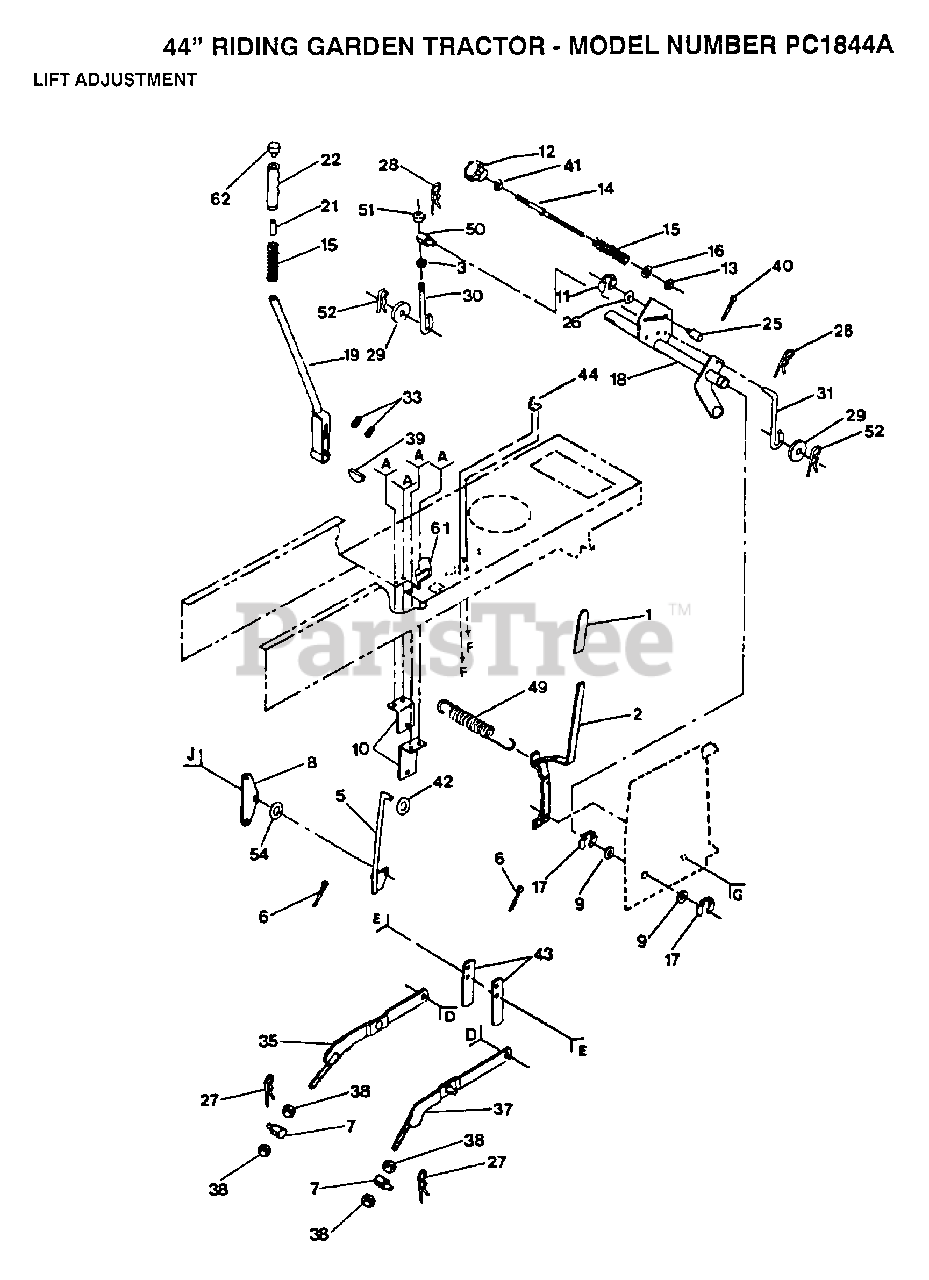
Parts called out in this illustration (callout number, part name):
5	ROD ASSEM YT
6	COTTER PIN
8	"T, BELLCRANK"
9	WASHER
10	"BRKT,BELLCRAN T"
11	KLIP RING
13	NUT T
14	ROD LIFT LT
15	SPRING T
16	WASHER
17	E-RING
22	GRIP
23	BOLT LT
25	TRUNION LT
26	WASHER
27	SPRING H
30	PIVOT PIN T
31	LIFT LINK LT
35	LH SUSP ARM ASM
36	"BOLT, SHOULDER LT"
37	RH SUSP ARM ASM
38	NUT
41	NUT
42	WASHER
43	UPSTOP
44	BRACKET LT
45	SCREW
49	"SPRING.EXT.8.5"""
51	NUT
52	SPRING.RETAINER
54	WASHER
55	WASHER T
56	NUT SPECIAL T
59	WASHER
